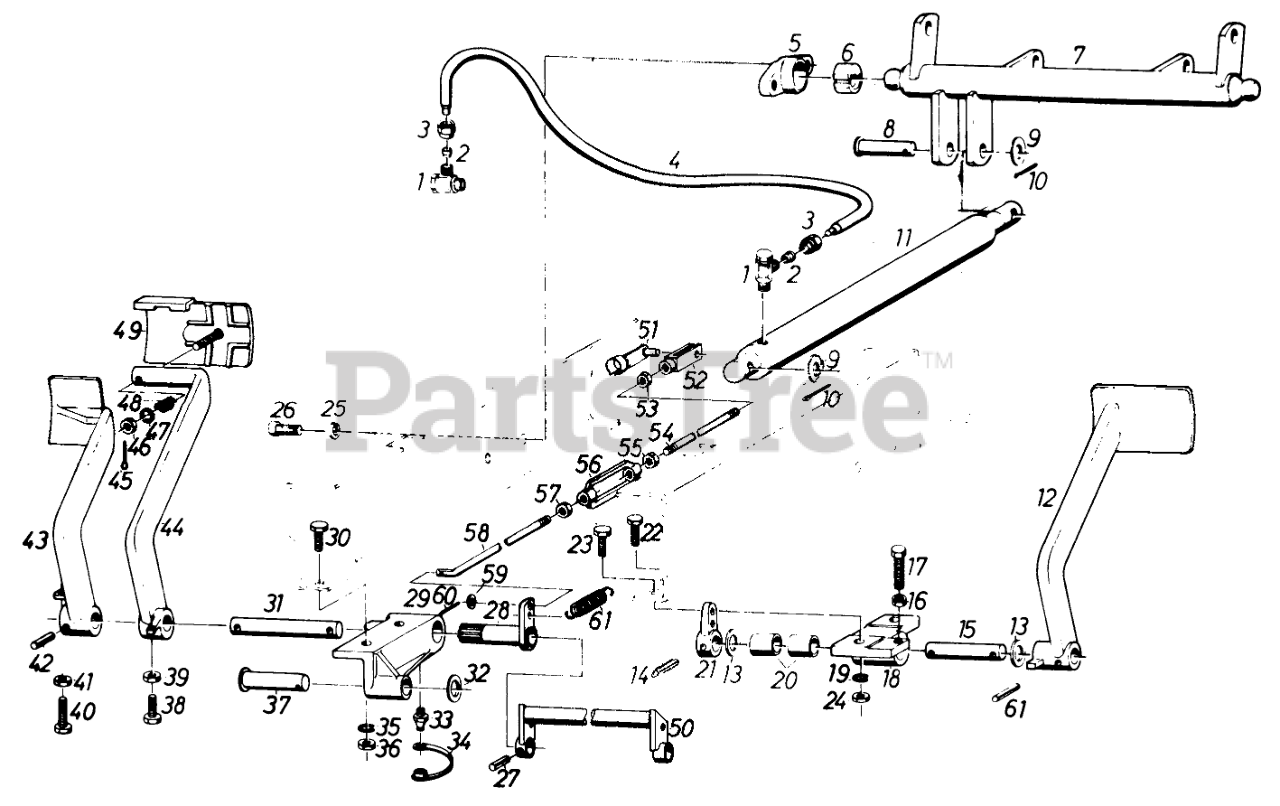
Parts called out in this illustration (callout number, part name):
1	JOINT (CONSISTS 2 PT
2	RING SEAL
4	High Pressure Hose (Order Parts No. 2 and 3 Also)
5	Flange
6	Bearing
7	Lift Axle
9	Washer
11	Hydraulic Cylinder
12	Clutch Pedal
13	Shim (18 X 25 X 0.5)
15	Clutch Axle
18	Pedal Bearing Left Assy. (Only Deliverable Part 20)
19	Washer
20	Bearing
23	Bolt
25	Spring Washer
29	Pedal Bearing Right
30	Bolt
31	Axle
32	Washer
33	Grease Zerk
35	Washer
43	Brake Pedal
44	Brake Pedal Assy. (Consists of Parts 44-49)
45	Split Pin
47	Washer
48	Spring
49	Plate Assy
50	Axle Assy
54	Brake Rod
56	Tension Screw
58	Brake Rod
59	Washer
60	Split Pin
